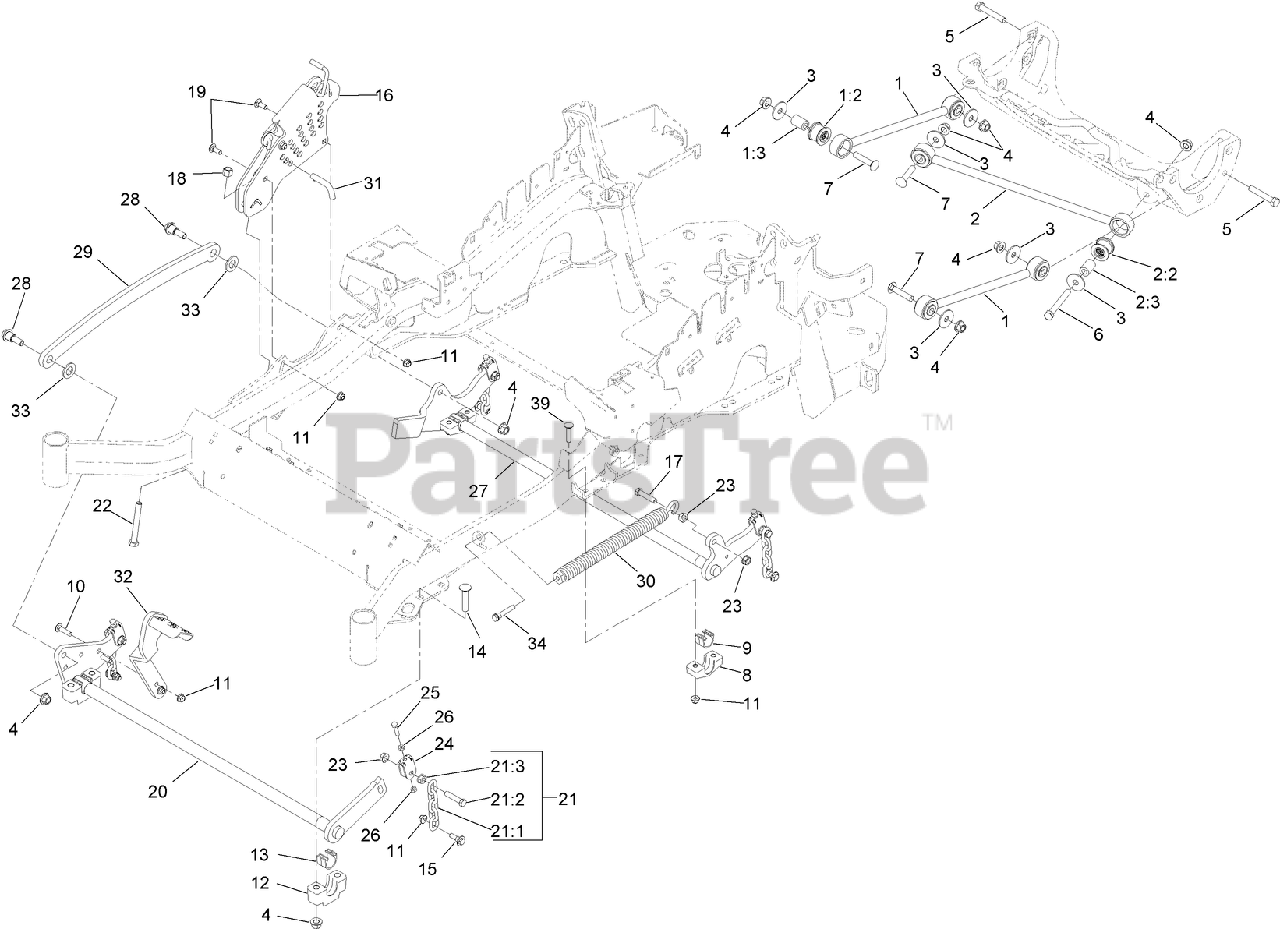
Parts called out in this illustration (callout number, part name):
1	DECK STRUT ASM
1:2	BUSHING-SUSPENSION, RUBBER
1:3	SPACER
2	PANHARD ROD ASM
2:2	BUSHING-SUSPENSION, RUBBER
2:3	SPACER
3	WASHER-THRUST
4	NUT-LOCK
5	SCREW-HH
6	SCREW-HH
7	SCREW-CARR
8	SUPPORT-CROSS SHAFT, REAR BEARING
9	BEARING-CROSS SHAFT, REAR
10	SCREW-CARR
11	NUT-HF, NI
12	SUPPORT-CROSS SHAFT, BEARING
13	BEARING-CROSS SHAFT, FRONT
14	BOLT-CARR
15	SCREW-SHOULDER, HHF
16	HOC ASM
17	SCREW-HH
18	NUT-LOCK, NI
19	BOLT-CARR
20	CROSS SHAFT-FRONT
21	DECK LIFT CHAIN ASM
21:1	CHAIN-LIFT, DECK
21:2	SCREW-HH
21:3	NUT-HF
22	BOLT-TAP
23	NUT-HF
24	YOKE-ADJUST, DECK
25	SCREW-HH
26	NUT-JAM
27	LIFT-DECK, REAR
28	SCREW-SHOULDER, HHF
29	LINK-LIFT, DECK
30	SPRING-EXTENSION
31	PIN-HOC
32	LEVER-FOOT
33	WASHER-FLAT
34	BOLT-SHOULDER
39	SCREW-CARR
